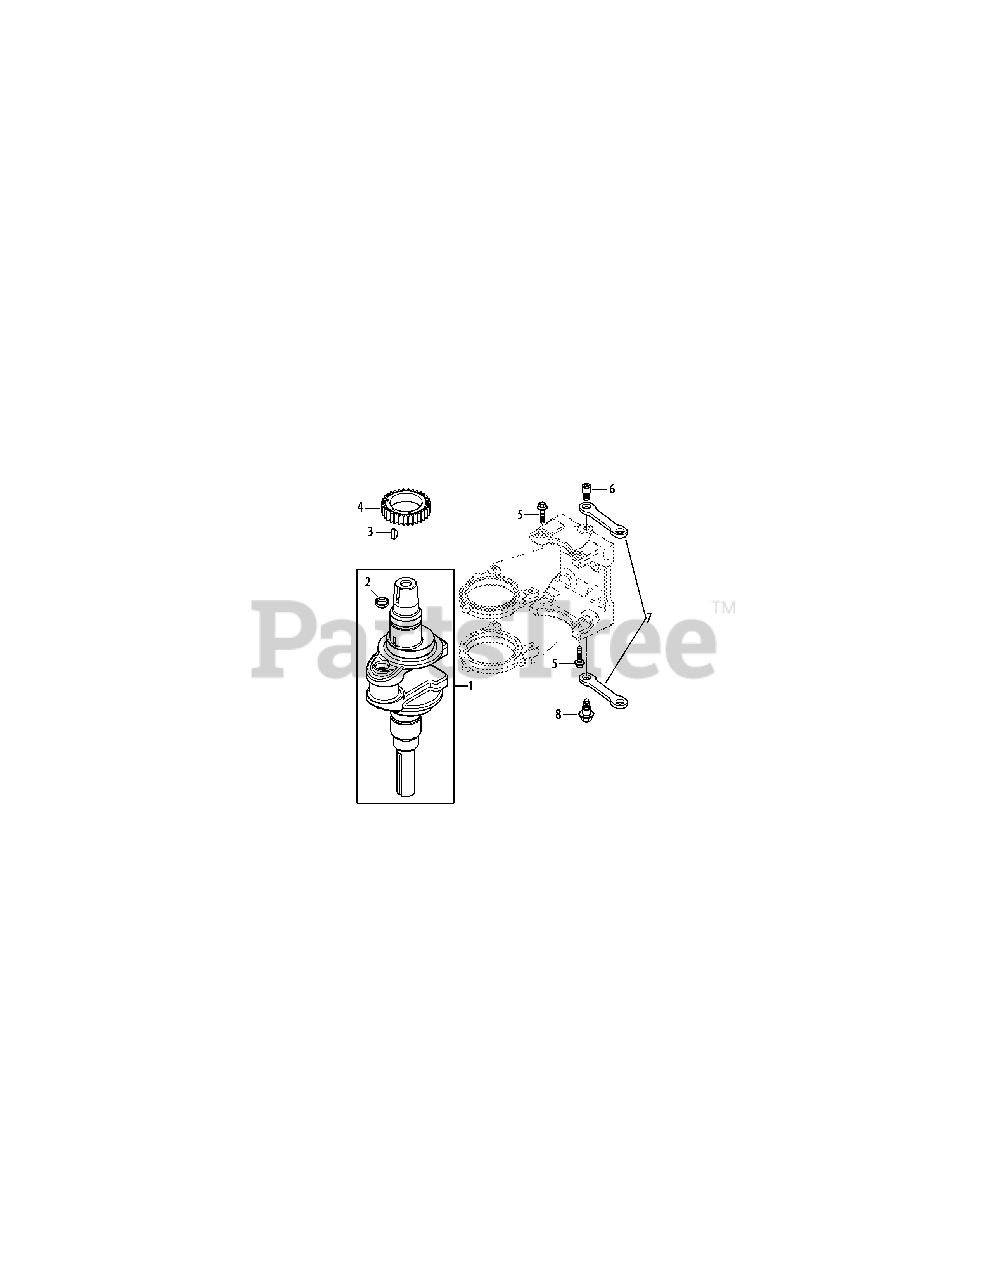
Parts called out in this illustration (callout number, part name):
1	Crankshaft Assembly Kit
3	Key, 3/16 X 5/8
4	Crankshaft Gear
5	Flange Screw, M6 X 1.0 X 25
6	Link Pivot Screw
7	Balance Weight Linkage
8	Shoulder Screw
